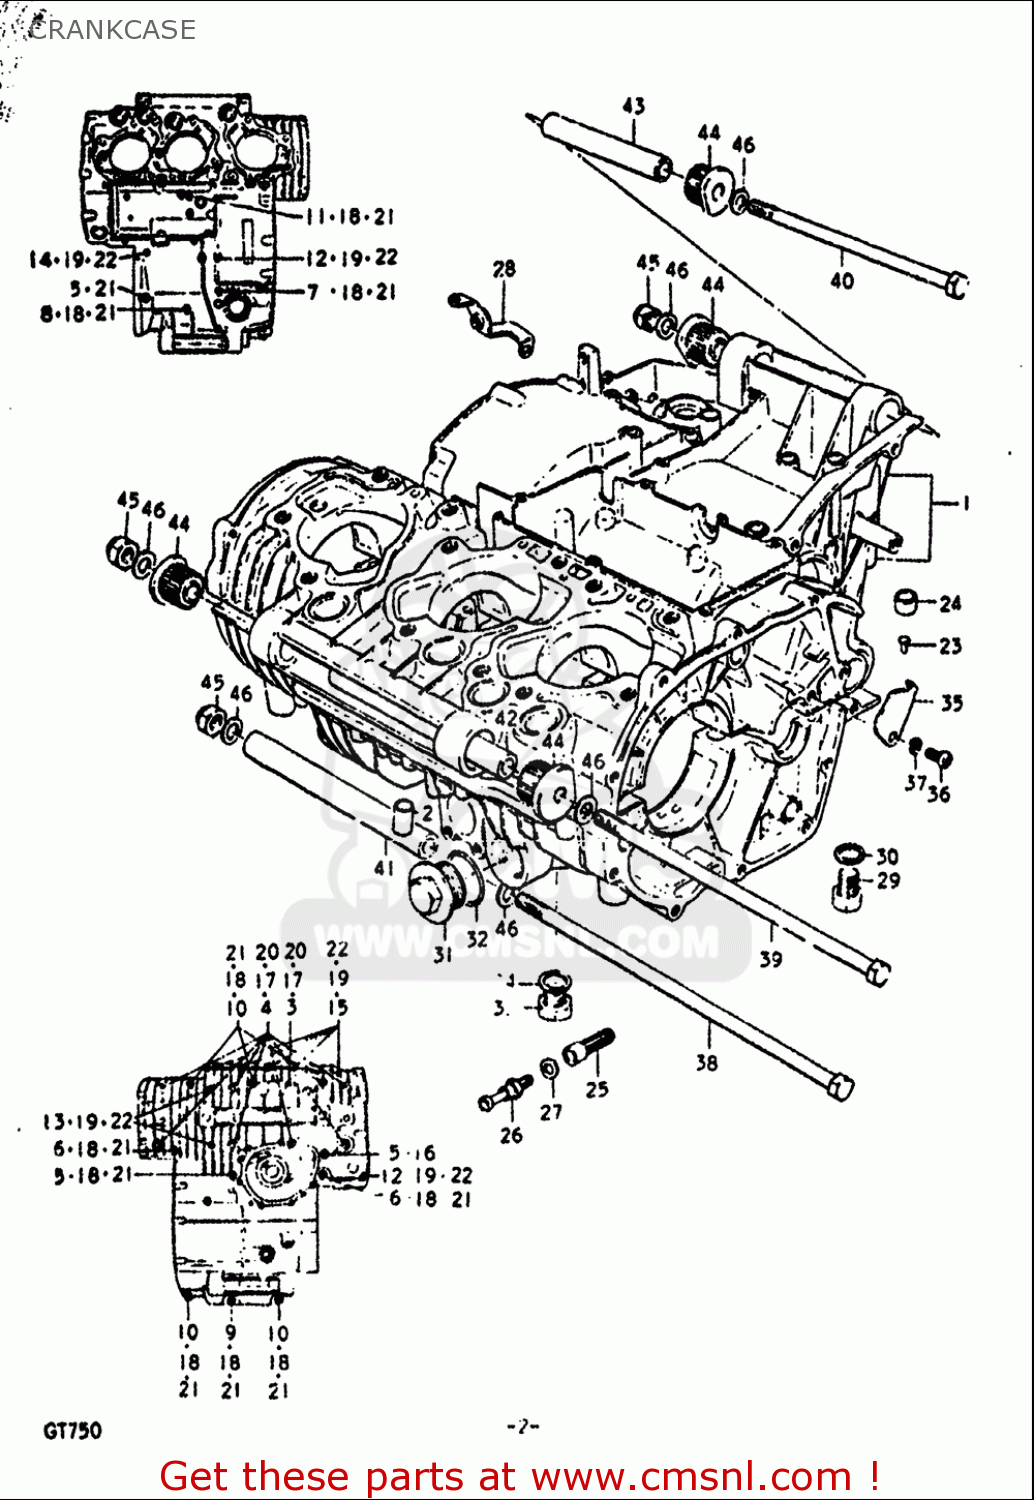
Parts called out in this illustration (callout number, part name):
2	PIN
3	BOLT
6	BOLT
7	BOLT
8	BOLT
9	BOLT
11	BOLT
12	BOLT 6X110
13	BOLT 6X95 HEXAG
14	BOLT
15	BOLT(6X35)
16	GASKET(8.2X14X1) (NAS)
17	WASHER
18	WASHER
19	WASHER
20	WASHER,LOCK
21	WASHER,LOCK
22	WASHER,LOCK
23	RIVET
24	BUSHING
26	CHECK VALVE,SRIS
27	GASKET(8.2X14X1) (NAS)
29	PLUG
30	GASKET(14X19.2X2) (NAS)
32	O RING(D:1.9,ID:32.7)
33	PLUG(MAGNETO)
34	GASKET(14X19.2X2) (NAS)
36	SCREW
37	WASHER,LOCK
38	BOLT
39	BOLT 10X270
40	BOLT(10X185)
44	BUSH
45	NUT
46	WASHER
